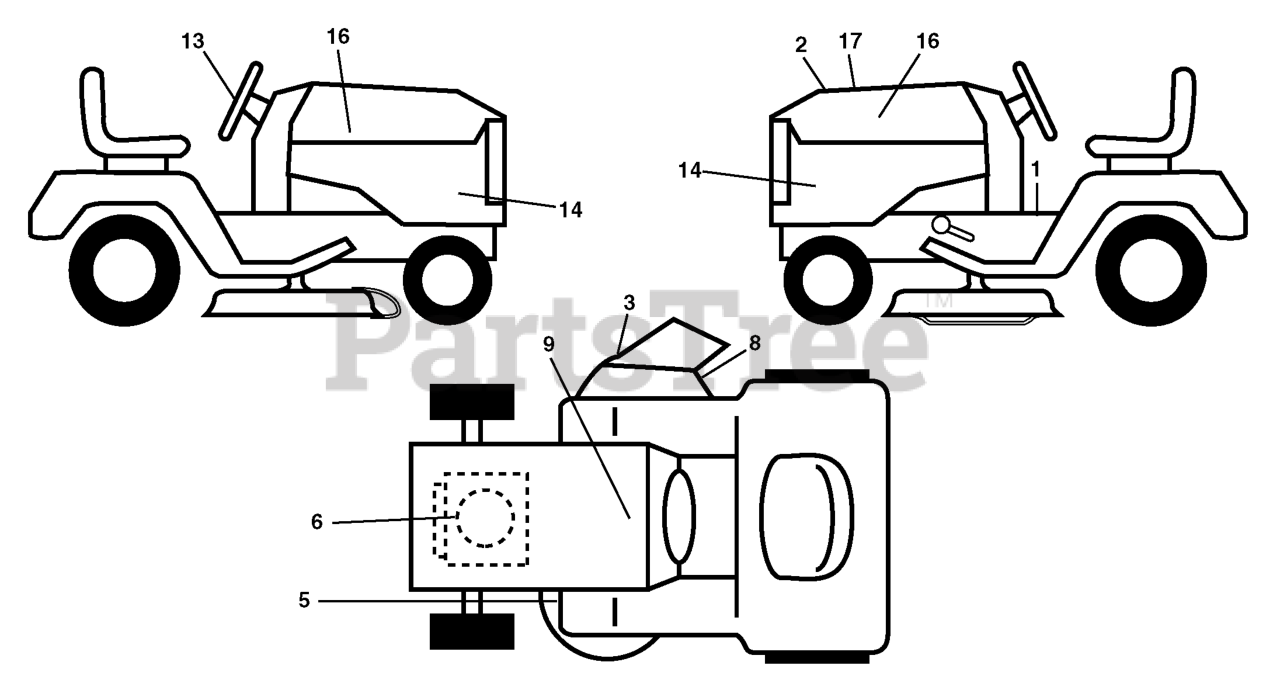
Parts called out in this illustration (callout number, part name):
1	DECAL.FENDER.OPER.TEX.
2	DECAL.HOOD.TOP.INSERT.
3	DECAL.WARN.KEEP.HAND.AWAY
5	DECAL CLUTCH/BRAKE
6	DECAL, ENG. HP
8	DECAL.MOWER.SCH.48/54
9	DECAL BTRY SYMBOLS
13	DECAL.WHEEL.STRG.LGN.H
14	DECAL, PANEL SIDE
16	DECAL.HOOD.NAMELOGO.HUSQ
17	DECAL.REPLACEMENT.960430035
17	DECAL.BYPASS.FENDER.CRD.LT.YT
